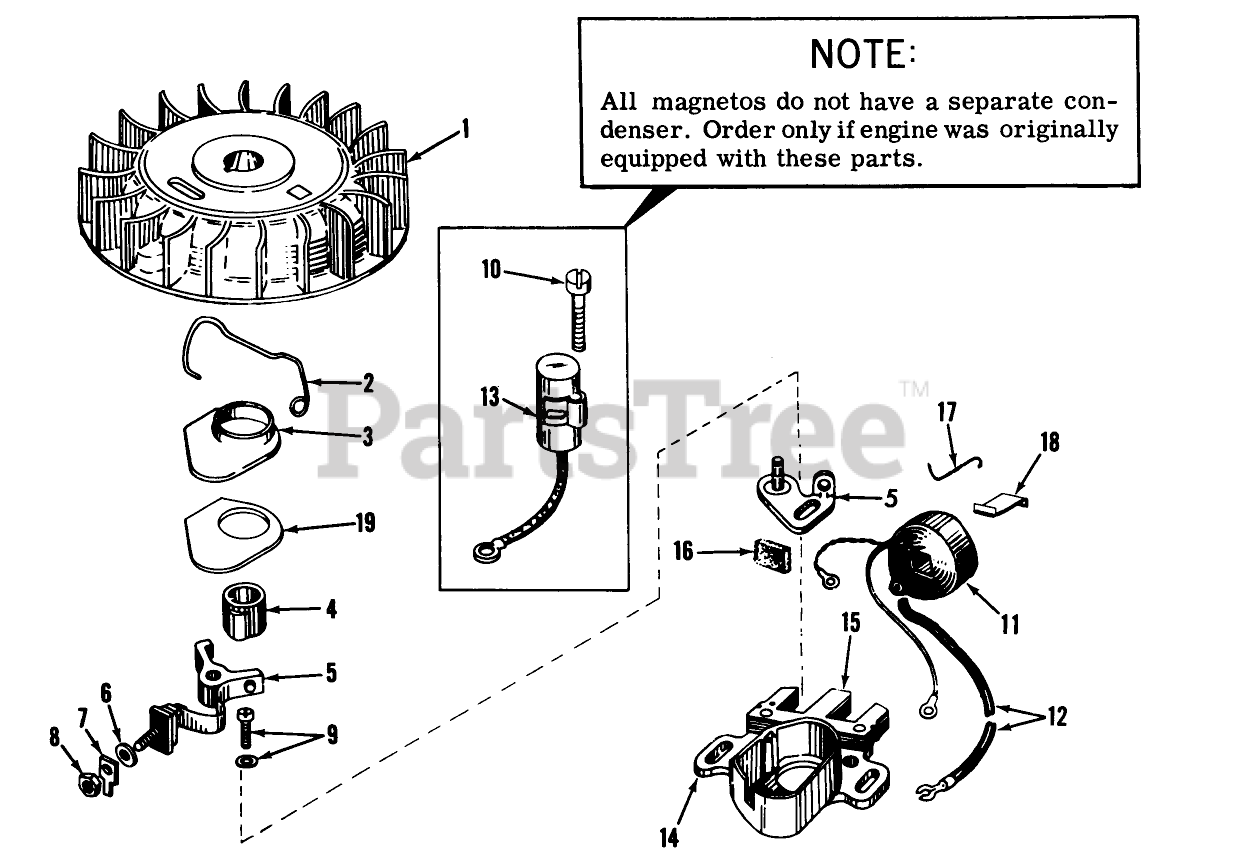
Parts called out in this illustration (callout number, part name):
1	Flywheel
2	Spring Breaker Box
3	Cover, Dust
4	Cam-Breaker
5	Breaker Assv.
6	Washer
7	Terminal
8	DECAL
9	Breaker Screw
10	Condenser Screw
11	Coil Assy., (Inc. Ref. Nos. 12, 13 18)
12	Wire, Lead
13	Condenser
14	Core Plate
15	A Stator Assy. (Incl. Nos. 5 thru 14, 16, 17 18)
16	Felt,Cam Wiper
17	Clip, Coil
18	Spring Coil Wedge
19	Gasket Dust
